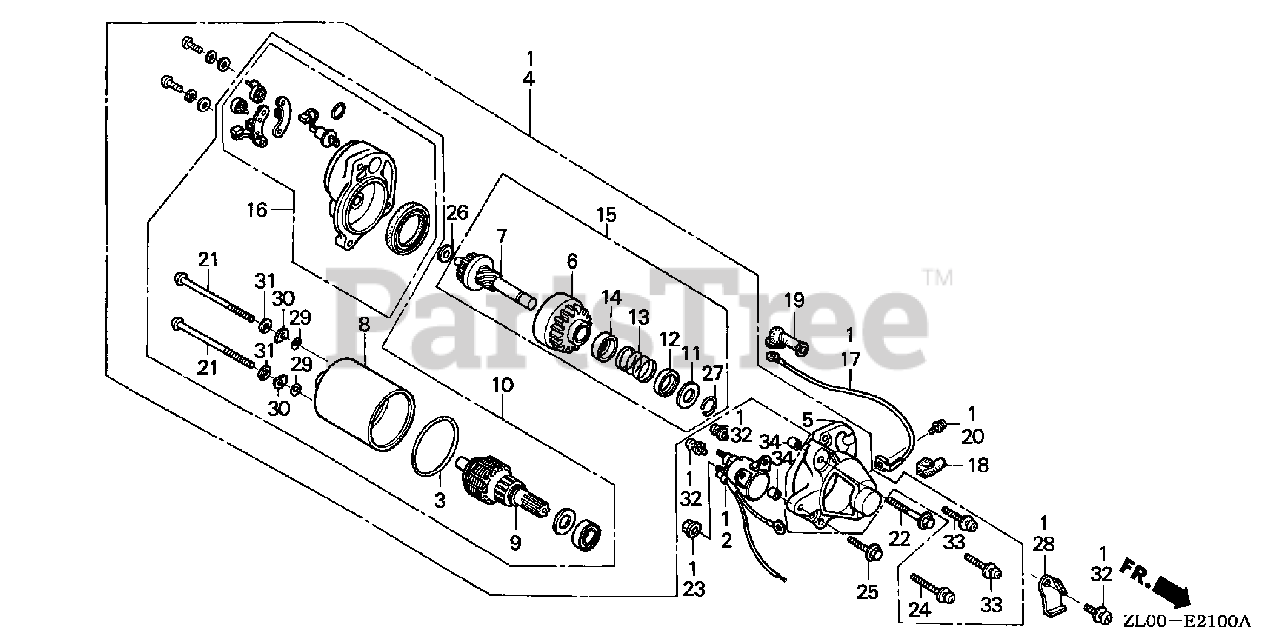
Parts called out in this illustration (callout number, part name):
1	MOTOR ASSY., STARTER
2	SWITCH, MAGNETIC
3	O-RING
4	MOTOR UNIT, STARTER
5	COVER, GEAR
6	PINION ASSY.
7	SHAFT UNIT, GEAR
8	YOKE ASSY.
9	ROTOR ASSY.
10	MOTOR ONLY
11	PIECE A, STOPPER
12	PIECE B, STOPPER
13	SPRING, RETURN
14	COVER, SPRING
15	GEAR ASSY.
16	BRACKET, FR.
17	WIRE, MAGNET SWITCH
18	COVER, MAGNET SWITCH TERMINAL
19	COVER, STARTER MOTOR TERMINAL
20	SCREW-WASHER (5X8)
21	BOLT, SETTING
22	BOLT, FLANGE (6X32)
23	NUT-WASHER (6MM)
24	SCREW-WASHER (5X30)
25	BOLT, FLANGE (6X25)
26	WASHER, PINION
27	CIRCLIP (10.2MM)
28	HOLDER, HARNESS
29	O-RING
30	WASHER, SPECIAL
31	WASHER, SPRING
32	SCREW-WASHER (5X14)
33	SCREW-WASHER (5X20)
34	PIN A, DOWEL (8X10)
